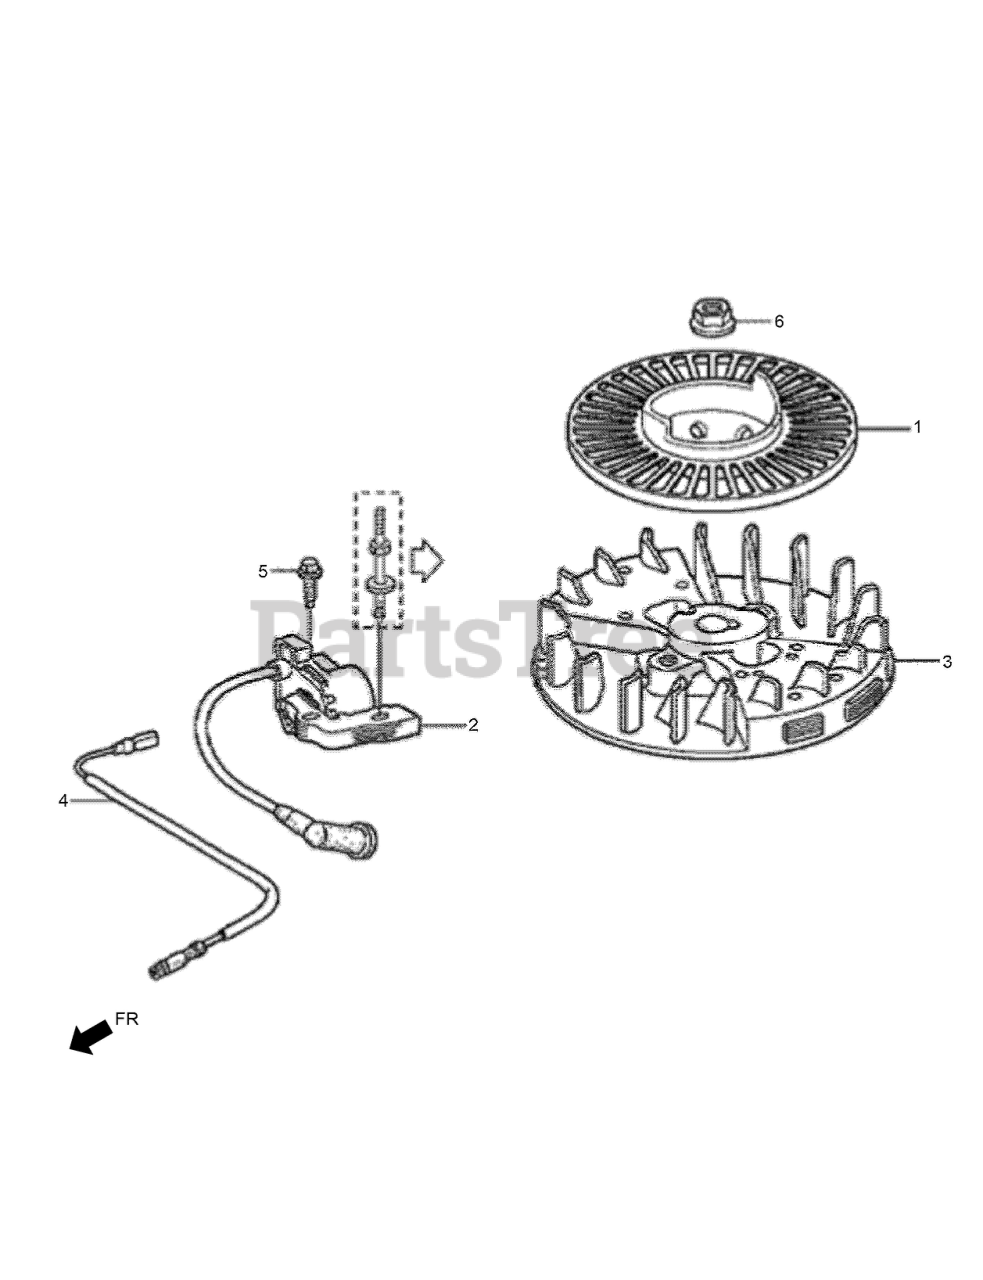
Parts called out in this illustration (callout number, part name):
1	STARTER PULLEY ASM
2	COIL ASM-IGNITION (to S/N 1001162)
2	COIL ASM-IGNITION (from S/N 1001163)
3	FLYWHEEL ASM
4	CORD-STOP SWITCH
5	BOLT-FLANGE-5X20
6	NUT-FLANGE-10MM
